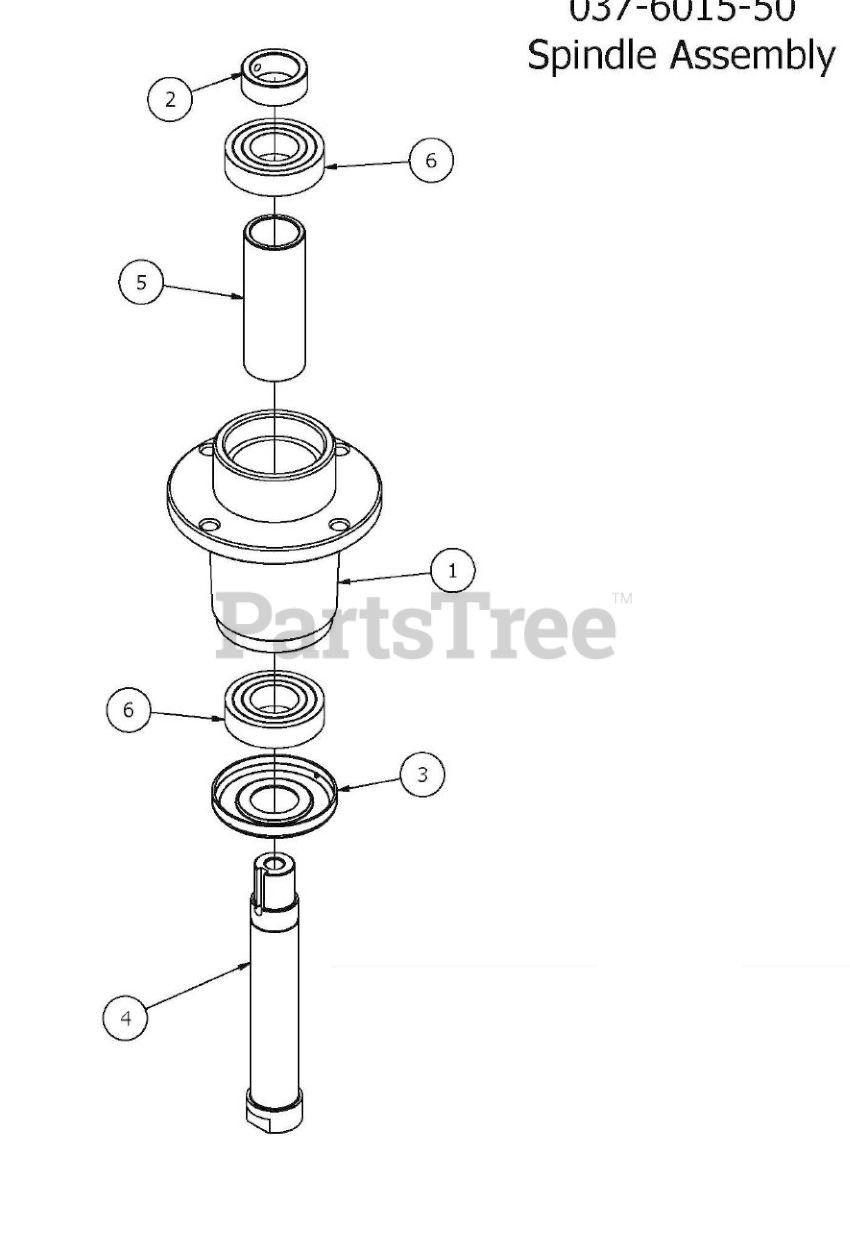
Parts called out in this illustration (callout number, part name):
1	Spindle Housing
2	Locking Collar w/ 1/4"-20 Set Screw
3	Spindle Dust Cap
4	Spindle Shaft
5	Spindle Spacer
6	Bearing - 6206
